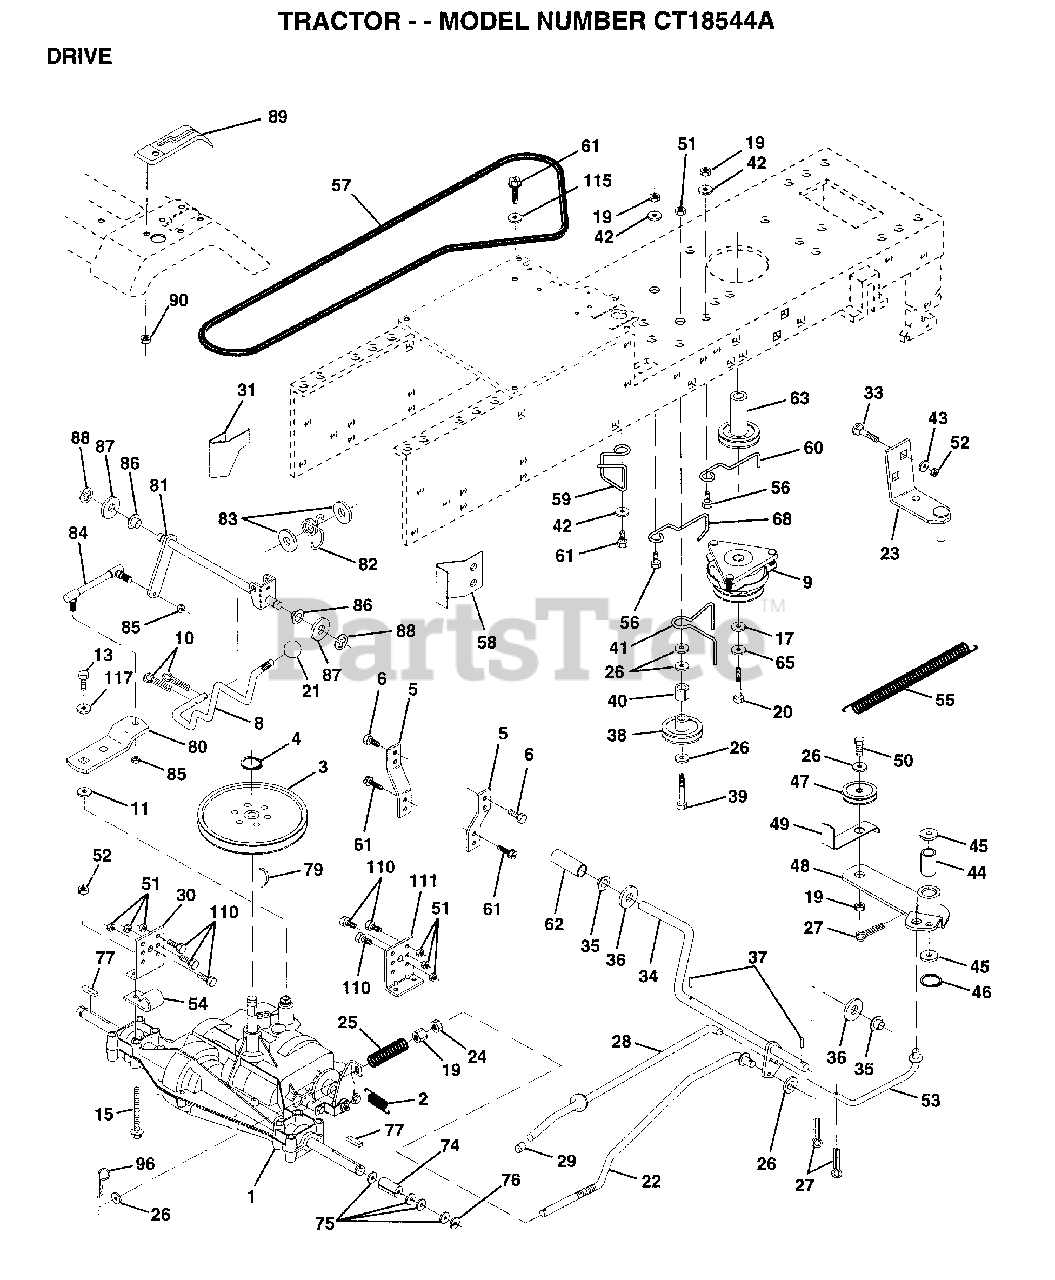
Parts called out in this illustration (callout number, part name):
1	TRANSAX. PRLES.
3	PULLEY TRANSAXLE
4	RING
5	STRAP TORQUE
6	SCREW
10	PIN COTTER 1/8
11	WASH-SHFT PLT LT
13	BOLT.1/4-28.W/PAT
15	BOLT.HX.FLG.5/16
17	WASHER
19	NUT
20	BOLT.7/16-20X4.25
21	CONTROL KNOB LT
22	ROD.ASM.BK.44.MWR
23	BRACKET.ASM.MTG
24	NUT
25	"SPRING,ROD BRAKE"
26	WASHER
27	COTTER PIN
28	ROD.BRAKE.PARK.LT
30	BRKT TRANS LH
31	KEEPER BELT LH
33	BOLT
34	SHAFT.PEDAL.FOOT
35	NYLON BEARING
36	WASHER LT
38	PULLEY.IDLER.FLAT
39	BOLT
40	SPACER T
41	BELT KEEPER LT
42	WASHER
43	WASHER T
44	"LY, BEARING"
45	WASHER LT
46	KLIP RING
48	ARM IDLER
49	RETAIN BELT
52	NUT
53	"LINK, CLUTCH T"
54	"CLIP,INSULATOR"
55	"SPRING, RETURN LT"
57	BELT.GRDRV.94.75
58	"KEEPER,BELT RH"
59	KEEPER BELT CNTSP
60	KEEPER BELT ENGLH
61	SCREW
62	PEDAL COVER T
63	PULLEY ENGINE
65	LOCKWASHER
68	"KEEPER,BLT ENG LT"
74	SPACER HYT
75	WASHER
76	E RING HYT
77	SQ KEY STD
80	"ARM,SHIFT"
81	"SHAFT,SHIFTER"
82	"SPRING,TORSION"
83	WASHER
84	"ROD,TIE "
85	NUT.CNT.LOCK.1/4
86	BUSHING
87	WASHER D
88	KLIP RING
89	CONSOLE SHIFTER
90	NUT
96	RETAINER M
100	WASHER M
111	BRKT TRANS RH
115	WASHER GT
117	WASHER PM
